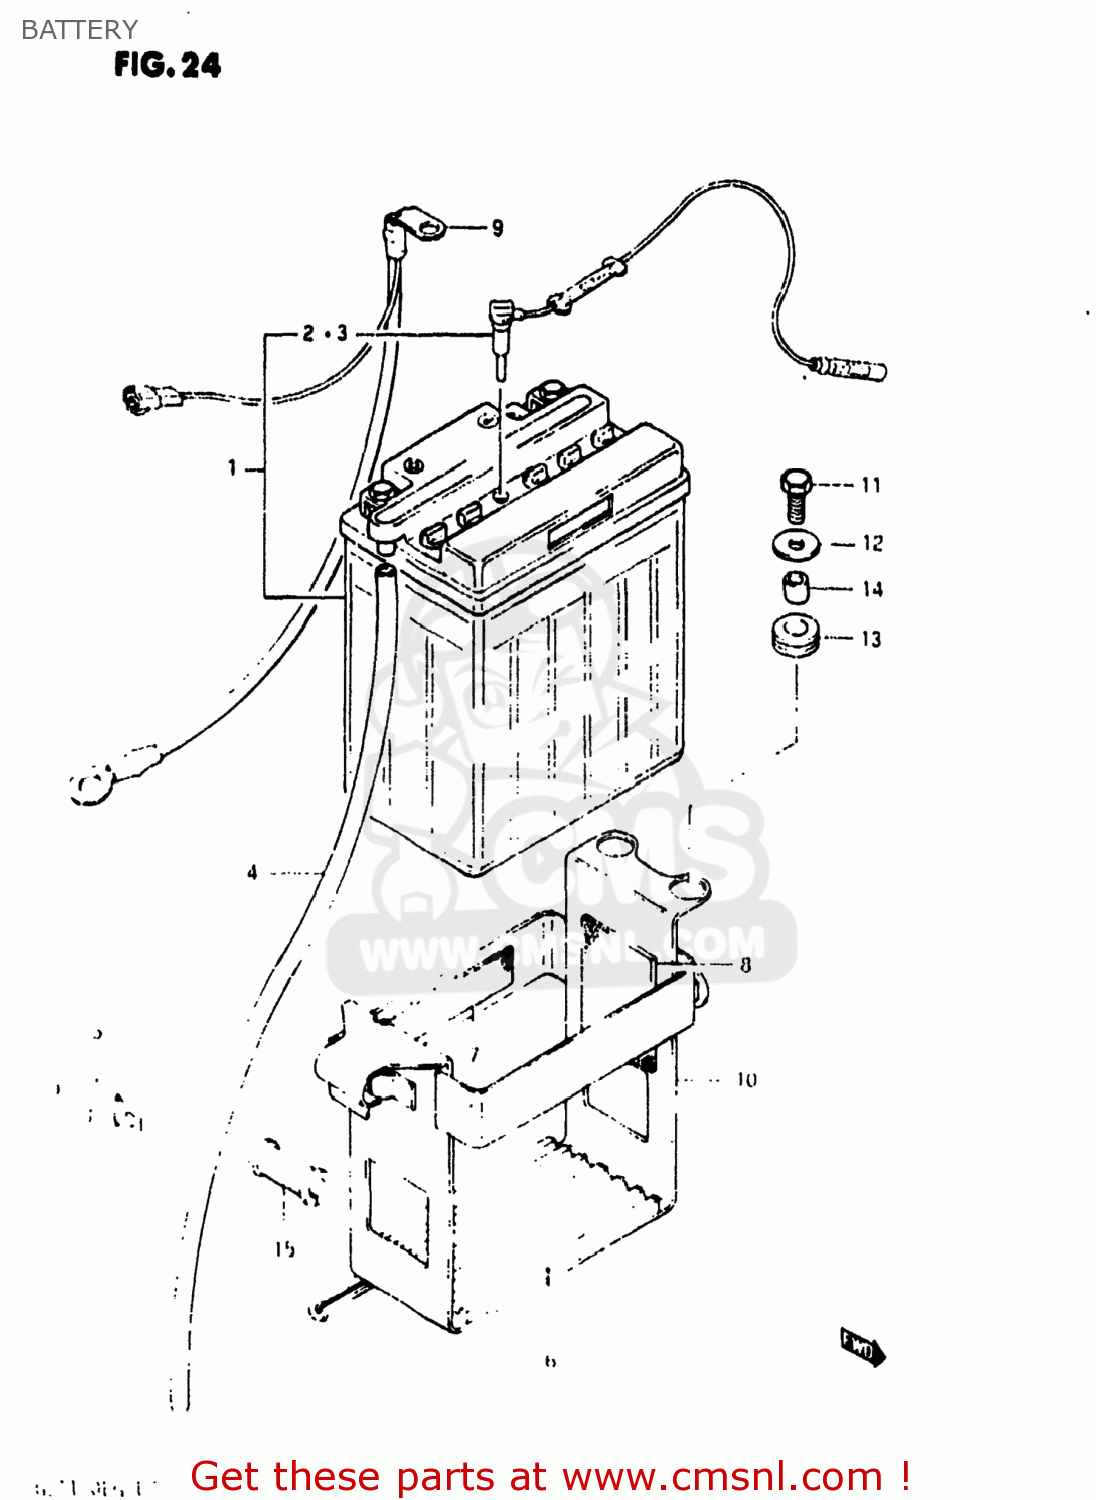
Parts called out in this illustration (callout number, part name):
1	BATTERY ASSEMBLY (12V)
2	SENSOR,BATTERY LEVEL
3	SENSOR,BATTERY LEVEL
4	HOSE,BATTERY EXHAUST
5	CLAMP
6	PROTECTOR,BATTERY
7	PROTECTOR(170X95X3.0)
8	PROTECTOR,BATTERY
9	WIRE,BATTERY MINUS LEAD
10	HOLDER,BATTERY
11	BOLT
12	WASHER
13	CUSHION
14	SPACER(6.1X9X7.5)
15	CUSHION
